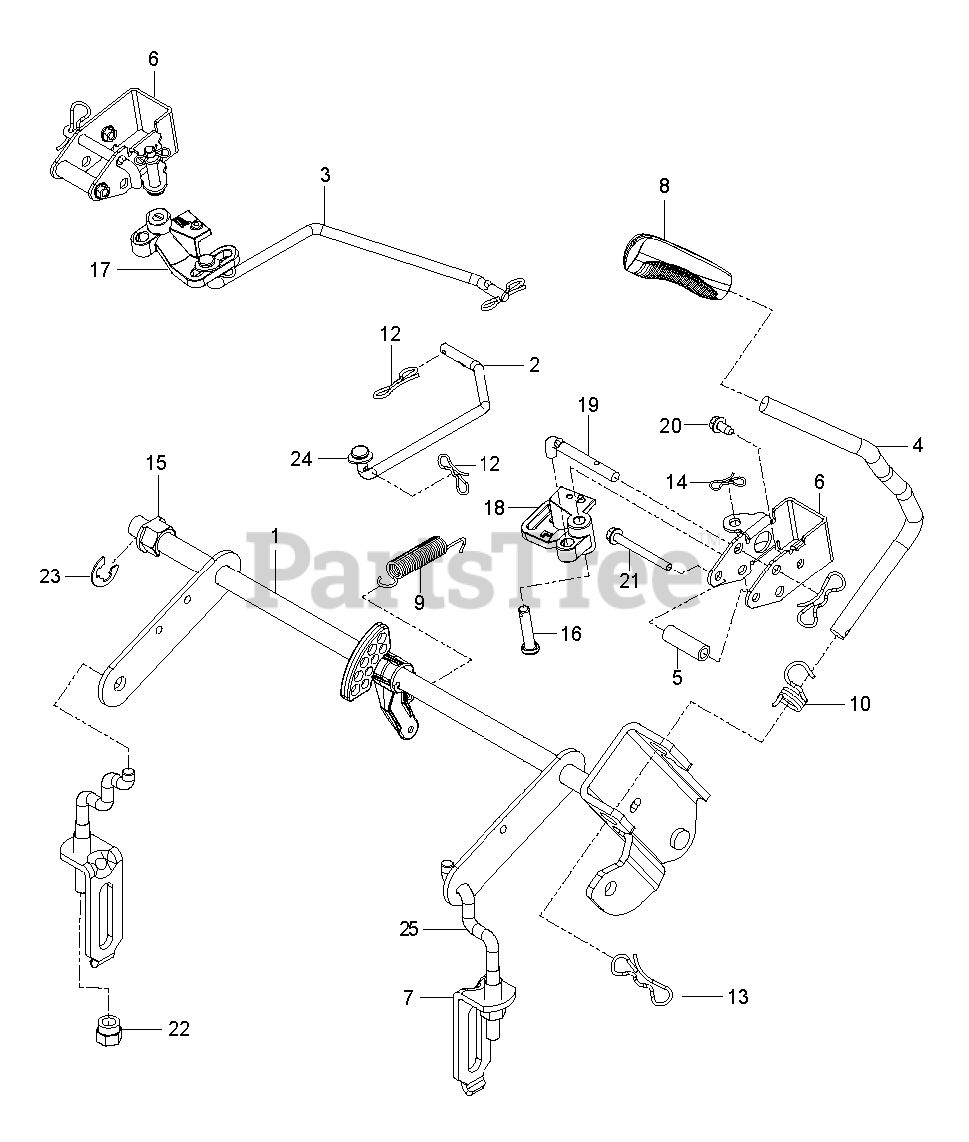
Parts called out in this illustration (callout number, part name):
1	SHAFT ASSY DECK LIFT WELDMENT
2	LINK.BRAKE.PARK.UPPER.LH
3	LINK.BRAKE.PARK.UPPER.RH
4	HANDLE LIFT ZTR
5	SPACER.334.ID.5.OD.1.5.L
6	BRACKET.BELLCRANK.PBRAKE X431
7	ASSEMBLY, BRKT LINK
8	GRIP.HANDLE.LIFT.PVC.BLACK
9	RETURN.BRAKE.PARK.AUTO
10	SPRING.TORSION.LIFT.HANDLE
12	PIN COTTER;LOCKING;BOWTIE;1IN
13	PIN.COTTER.7/16.BOW TI.
14	PIN.COTTER.5/16.BOW TI
15	PLASTIC NUT
16	PIN.5.16X1.5
17	BELLCRANK.RH
18	BELLCRANK.LH
19	ROD.PUSH.BRAKE
20	SCREW.1/4-20X5/8
21	SCREW THD;ROLL;1/4-20 X 2.25
22	NUT, LIFT LINK 7/16-20
23	RETAINING RING LT
24	WASHER
25	LINK, REAR SUSPENSION
